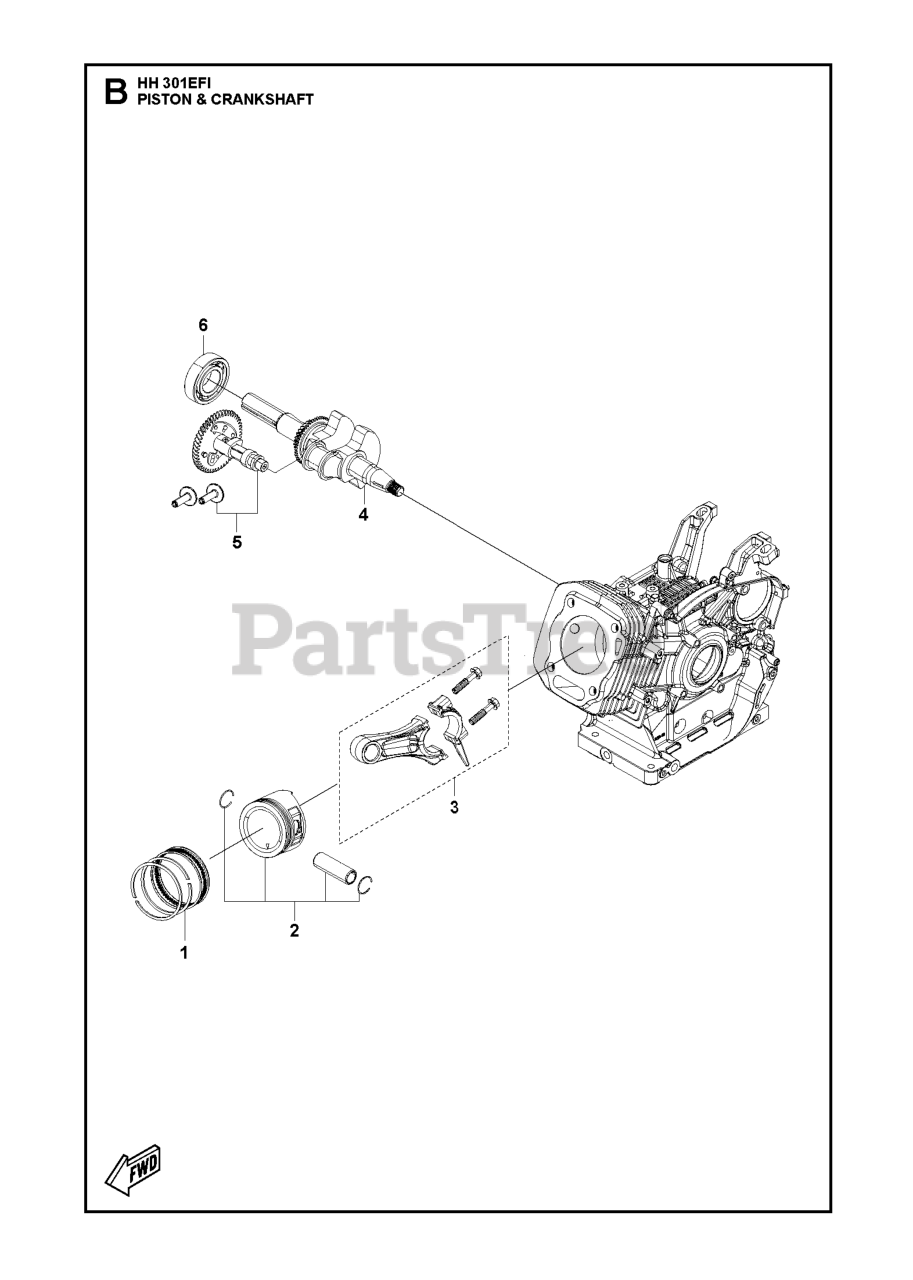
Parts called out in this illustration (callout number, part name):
1	PISTON RING SET
2	PISTON ASSY
3	CONNECTING ROD
4	CRANKSHAFT
5	CAMSHAFT KIT
6	BALL BEARING
